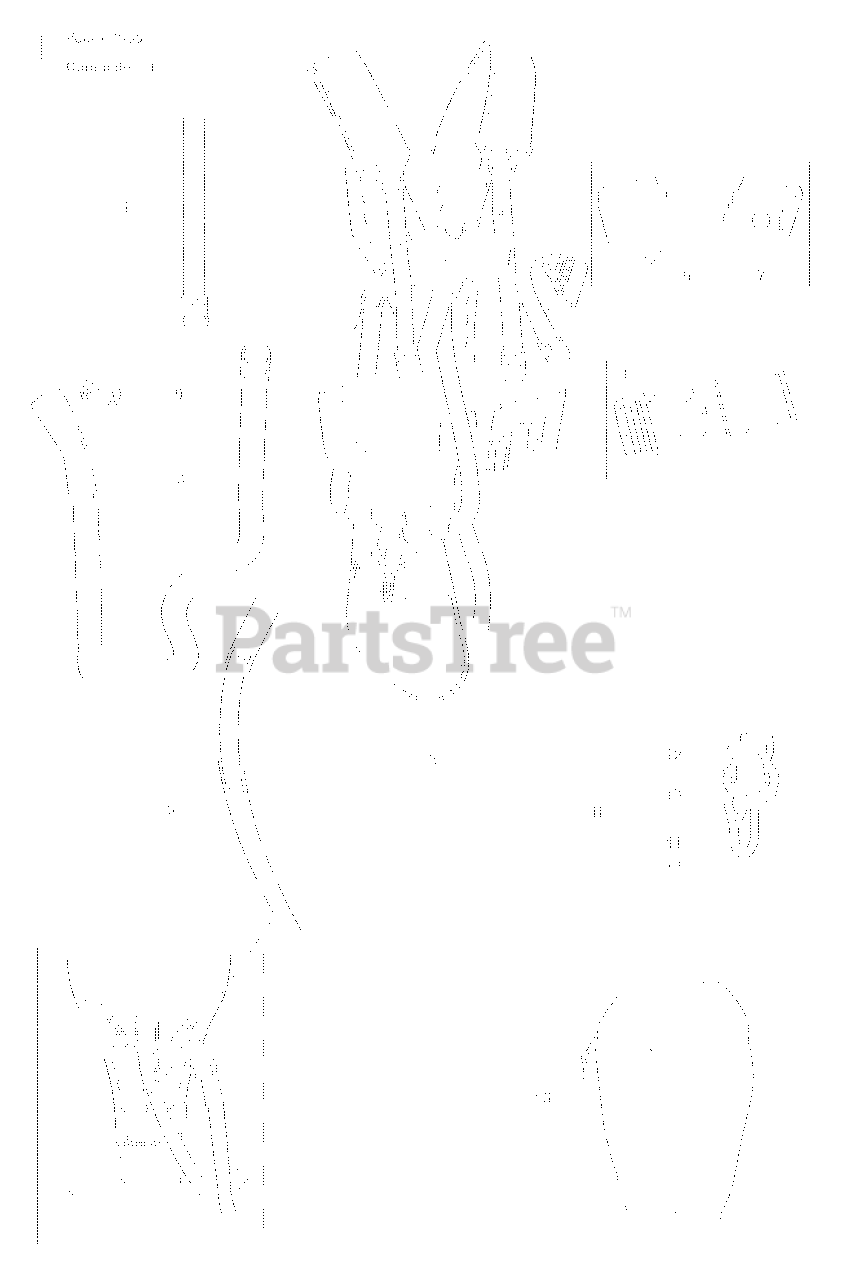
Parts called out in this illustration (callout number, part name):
6	FRONT PIECE
7	FRONT PIECE
9	CLIP
10	WELT HOOK
15	TOOL BAG
